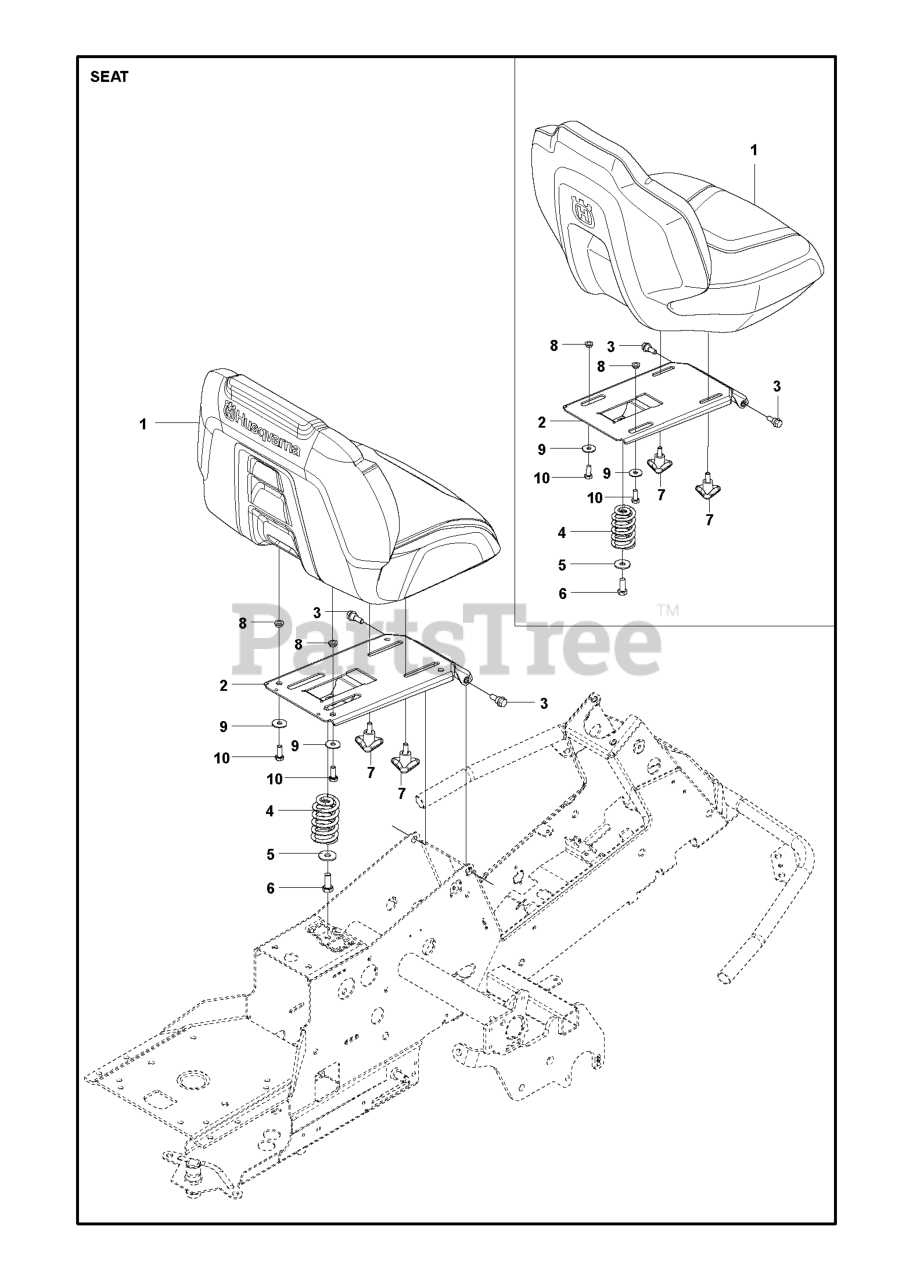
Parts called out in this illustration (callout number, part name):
1	SEAT HUSQVARNA LOW BACK
1	Seats
2	SEAT BRACKET ASSY
4	SEAT SPRING
6	Screw M10x25
